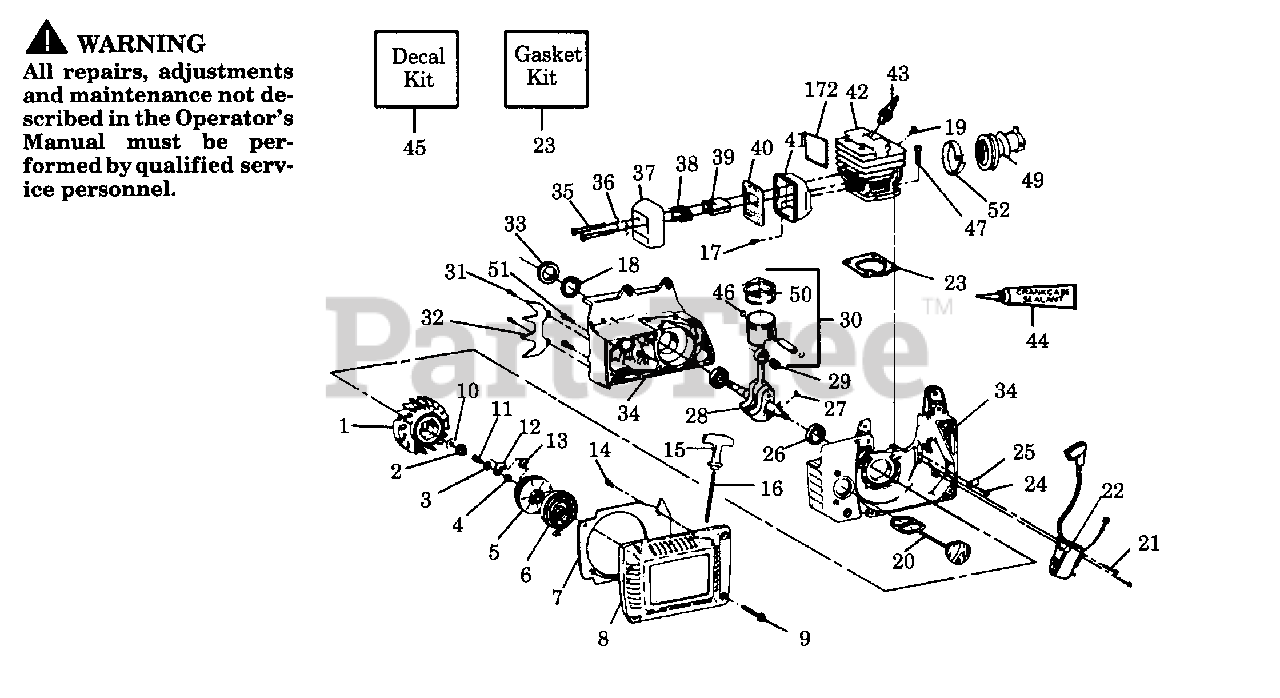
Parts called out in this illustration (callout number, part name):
1	Flywheel
3	Wave Washer
4	Retainer
5	Starter Pulley
6	Starter Spring
7	Baffle Plate
8	Fan Housing
9	Screw
12	Starter Cam
13	Starter Dog
15	Starter Handle
16	Rope Kit
18	Snap Ring
20	Oil Cap Ass'y.
21	Screw
22	Ignition Module
23	Gasket Set
26	Crankshaft Bearing
27	Flywheel Key
28	Crankshaft/Rod Ass'y.
29	Piston Pin Bearing
30	Model 2700,2800
30	Model 3000
30	Model 3100,3300
33	Crankshaft Seal
34	Crankcase Ass'y.
37	Muffler Cover
38	Spark Arrestor Screen
39	Muffler Diffuser
40	Muffler Baffle Plate
41	Muffler Body
42	Model 2700,2800
42	Model 3000
42	Model 3100,3300
43	Spark Plug (CJ-4)
45	Decal Kit
46	Retainer
49	Carburetor Adaptor
50	Model 2700,2800
50	Model 3000
50	Model 3100,3300
52	Clamp Ass'y.
172	Deflector (Model 3300 Only)
